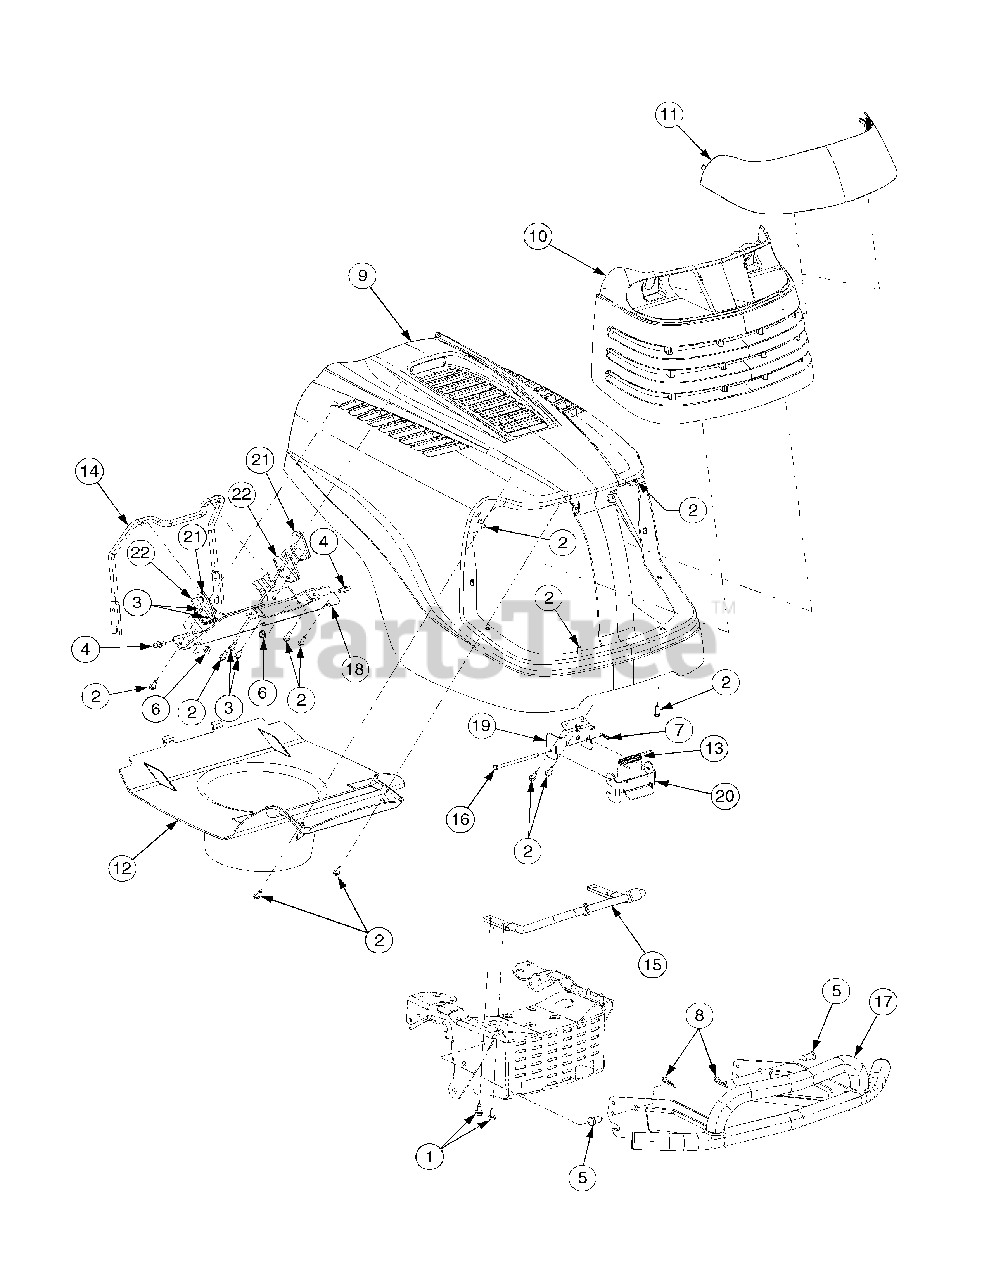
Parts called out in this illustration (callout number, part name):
1	Screw, Hx Wash. Hd Tapp, 5/16-12 x .75
2	Screw, Hx Wash. Hd Tapp, 1/4-15 x .75
3	Screw, Hx Wash. Hd Tapp, 1/4-20 x .75
4	Screw, Ball, 5/16-18
5	Pin,Clevis, .5 x .78
6	Nut, Flange Lock, 5/16-18 GR5
7	Pin, Internal Cotter
8	Pin, Internal Cotter
9	Hood
10	Grill
10	Miniature Lamp, 12 V
10	Lamp Socket
11	Lens, Hood
12	Plenum, Hood
13	Spring, Latch, Hood
14	Rod, Hood Pivot
15	Rod, Hood Latch
16	Rod, .25 x 4.55
20	Bracket, Latch Pivot
21	Bracket, Upper Pivot
22	Bracket, Hood Pivot
